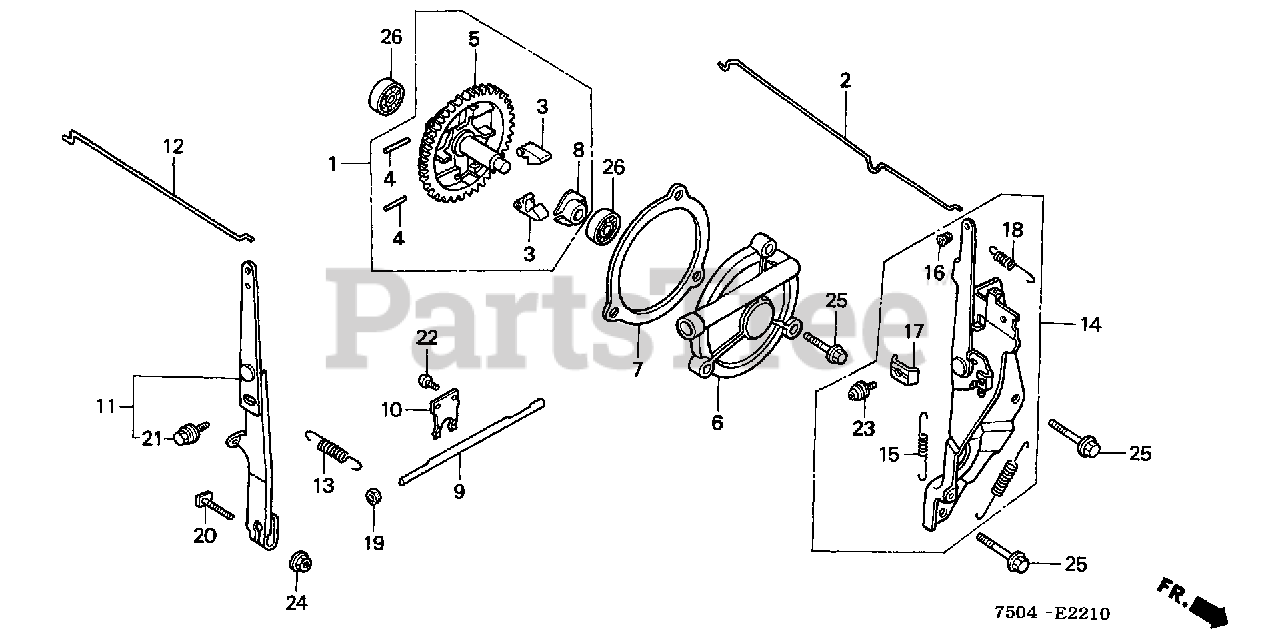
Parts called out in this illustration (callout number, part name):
1	GOVERNOR KIT
2	ROD, CHOKE
3	WEIGHT, GOVERNOR
4	PIN, GOVERNOR WEIGHT
5	SHAFT, GOVERNOR
6	COVER, GOVERNOR
7	GASKET, GOVERNOR COVER
8	SLIDER, GOVERNOR
9	SHAFT, GOVERNOR ARM
10	FORK, GOVERNOR
11	ARM, GOVERNOR
12	ROD, GOVERNOR
13	SPRING, GOVERNOR
14	CONTROL
15	SPRING, CONTROL LEVER RETURN
16	COLLAR, LEVER
17	HOLDER, CABLE
18	SPRING, CABLE RETURN
19	OIL SEAL (8X14X5)
20	BOLT, GOVERNOR ARM
20	BOLT, HEX. (6X22)
21	BOLT-WASHER (6X12)
22	SCREW, PAN (3X8)
23	SCREW-WASHER (5X16)
23	SCREW-WASHER (5X20)
24	NUT, FLANGE (6MM)
25	BOLT, FLANGE (6X25)
26	BEARING, RADIAL BALL (6000)
